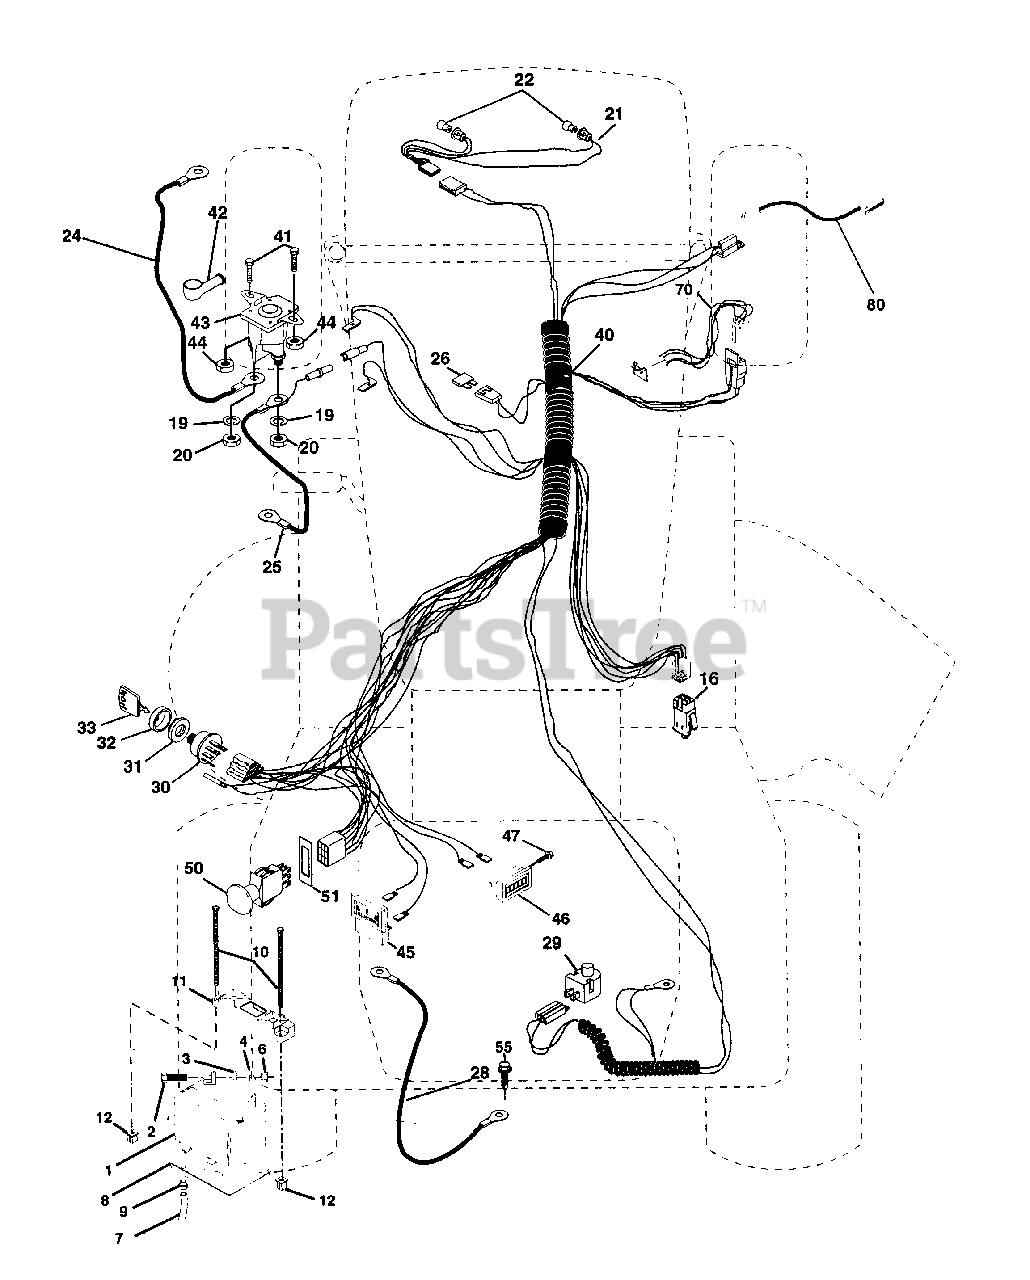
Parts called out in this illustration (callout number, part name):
1	Battery 12 Volt 25 AMP
2	Bolt Hex Hd 1/4-20unc X 3/4
3	Washer 9/32 X 5/8 X 16 Ga.
4	Washer Lock Hvy Helical 1/4
6	Nut Fin Hex 1/4-20 Unc
7	Tube Plastic 46"
8	Tray Battery 7.80 x 5.25 Blk
9	Clamp Hose Olive
10	Bolt Btr Frt 1/2-20 x 7.5 Zinc
11	Holddown Battery Front Mount
12	Nut Push Nylon 1/4" Battery Frt
16	Switch Interlock Push-In
19	Washer Lock 1/4
20	Nut Jam Hex 1/4-20 Unc
21	Harness Asm Light W/4152j
22	Bulb Light #1156
24	Cable Battery 6 Ga 11" red
25	Cable Battery 6 Ga 44" red w/16 wire
26	Fuse 30 AMP Auto Green
28	Cable Ground 6 Ga 21" black
29	Switch Plunger Nc Gray
30	Switch Ign 4 pos w/lights
31	Nut Ignition
32	Cover Sw Ignition
33	Key Ign Modelled Generic
40	Harness Ign.
41	Bolt Blk Fin Hex 1/4 - 20 x 1/2
42	Cover Terminal Red
43	Solenoid
44	Nut Keps Hex 1/4-20 Unc
45	Ammeter Rectangular 6 Amp
46	Meter Hour
47	Screw 10-24 x 1/2 Black
50	Switch PTO 3PDT Black Delta 96
51	Ring Retainer PTO
55	Screw Thdrol 5/16-18 x 1/2 Tyt
70	Harness, Eng Kohl Cmd-L Dual
80	Harness Clutch Evx
